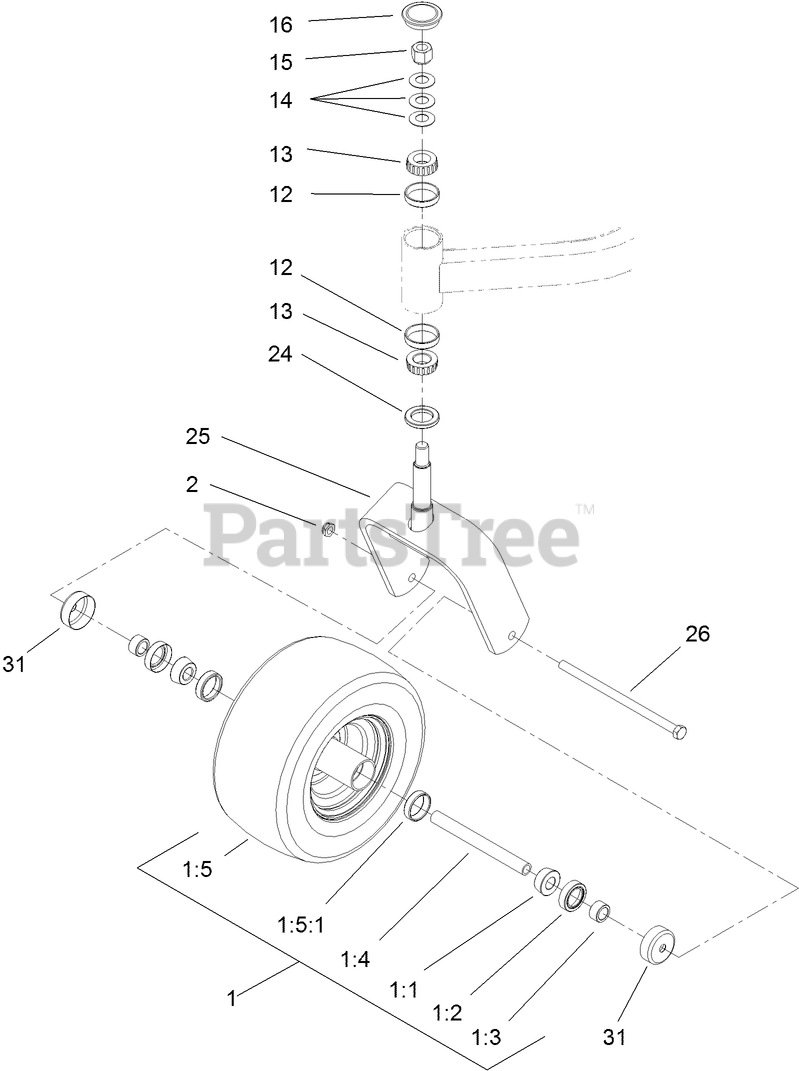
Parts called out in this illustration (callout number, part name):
1	WHEEL AND BEARING ASM
1:1	BEARING-CONE, TAPER
1:2	SEAL-CASTER
1:3	SPACER-NUT
1:5	Deck ASM
1:5:1	BEARING-CUP
2	NUT-HEX
12	BEARING-CUP, TAPERED
13	BEARING-CONE, TAPERED
14	WASHER-BELLVILLE
15	NUT-LOCK, NI
16	CAP-GREASE
24	SEAL-GREASE
26	SCREW-HH
31	GUARD-SEAL
